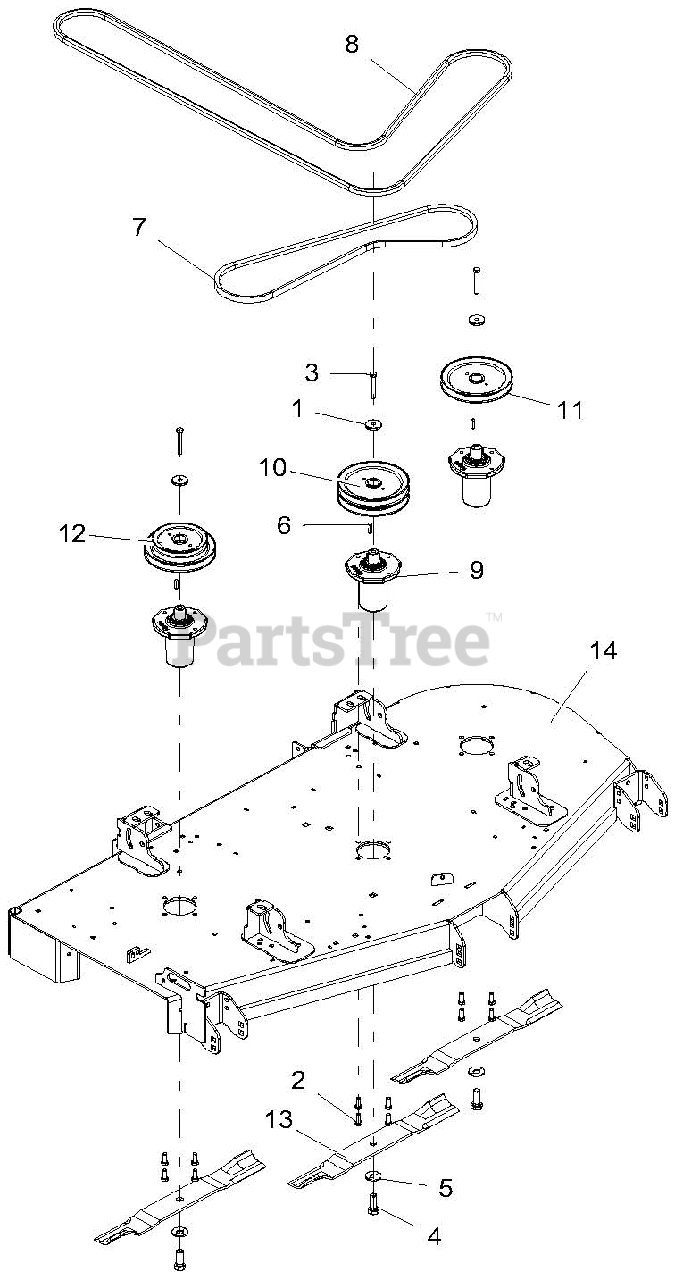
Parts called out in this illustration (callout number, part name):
1	RETAINER, SHEAVE SPINDLE
2	BLT-HEX .38-16X1.00 GR5 YWZC EP30
3	BLT-HEX .38-16X2.75 GR8 YWZC
4	BLT, HEX .62-18X1.75 GR8 YWZC
5	WSHR, BLVL .63X1.625X.14
6	KEY-SQ .250X.250X1.00 RC 40-50
7	BELT, B 63.00 RAW COGGED
8	BELT, BB 118.00 WRAPPED HEX
9	SERVICE, ASM SPINDLE- DUCTILE
10	PULLEY, DOUBLE 1"ID X 6.75"OD-BLACK
11	PULLEY, V-1" ID X 6.75" OD-BLACK
12	PULLEY, DOUBLE -1" ID X 6.75" & 5.25" OD
13	BLADE, MOWER 60"
14	WLDMT, 60" SIDE DISCH DECK
